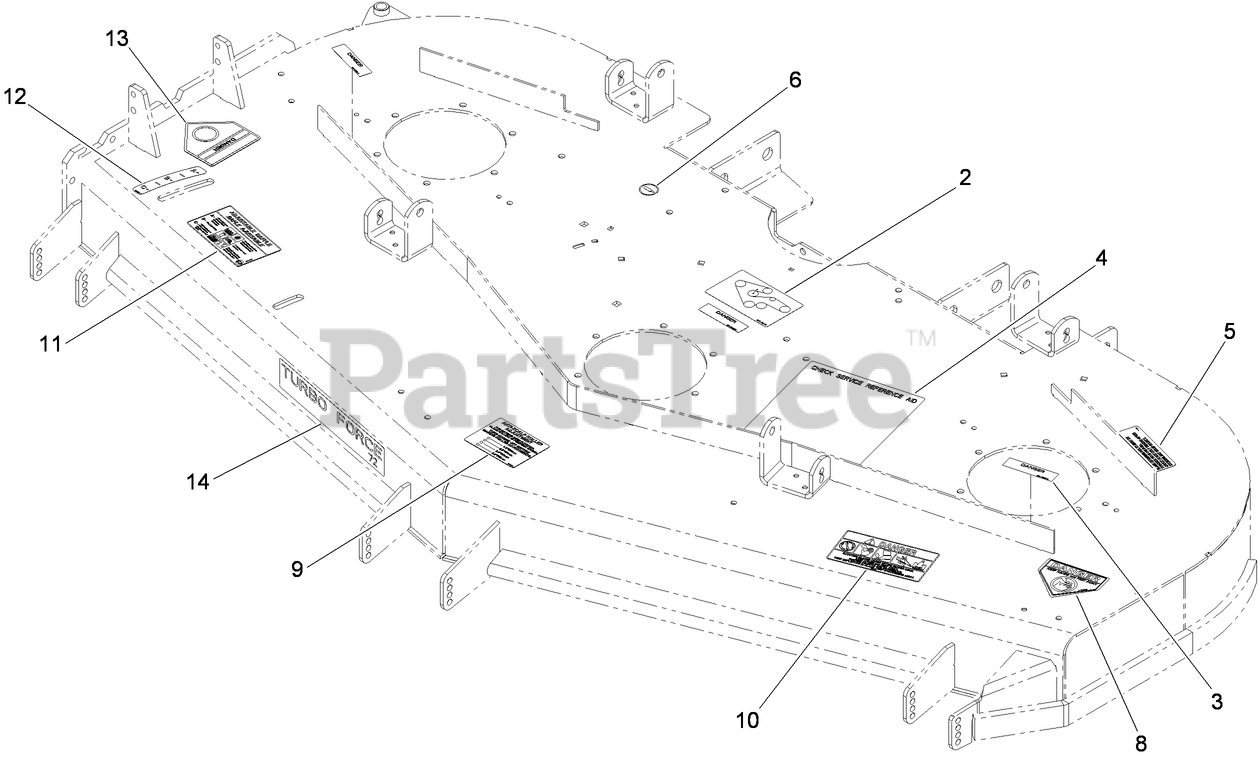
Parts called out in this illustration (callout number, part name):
2	DECAL-ROUTING, BELT
3	DECAL-COVER, MISSING
4	DECAL-CHECK, SERVICE
5	DECAL-TORQUE
6	DECAL-GREASE
8	DECAL-DANGER
9	DECAL-SCALP, ANTI
10	DECAL-DANGER, THROWN OBJECT
11	DECAL-ADJUSTMENT, BAFFLE
12	DECAL-SETTING, BAFFLE
13	DECAL-DANGER
